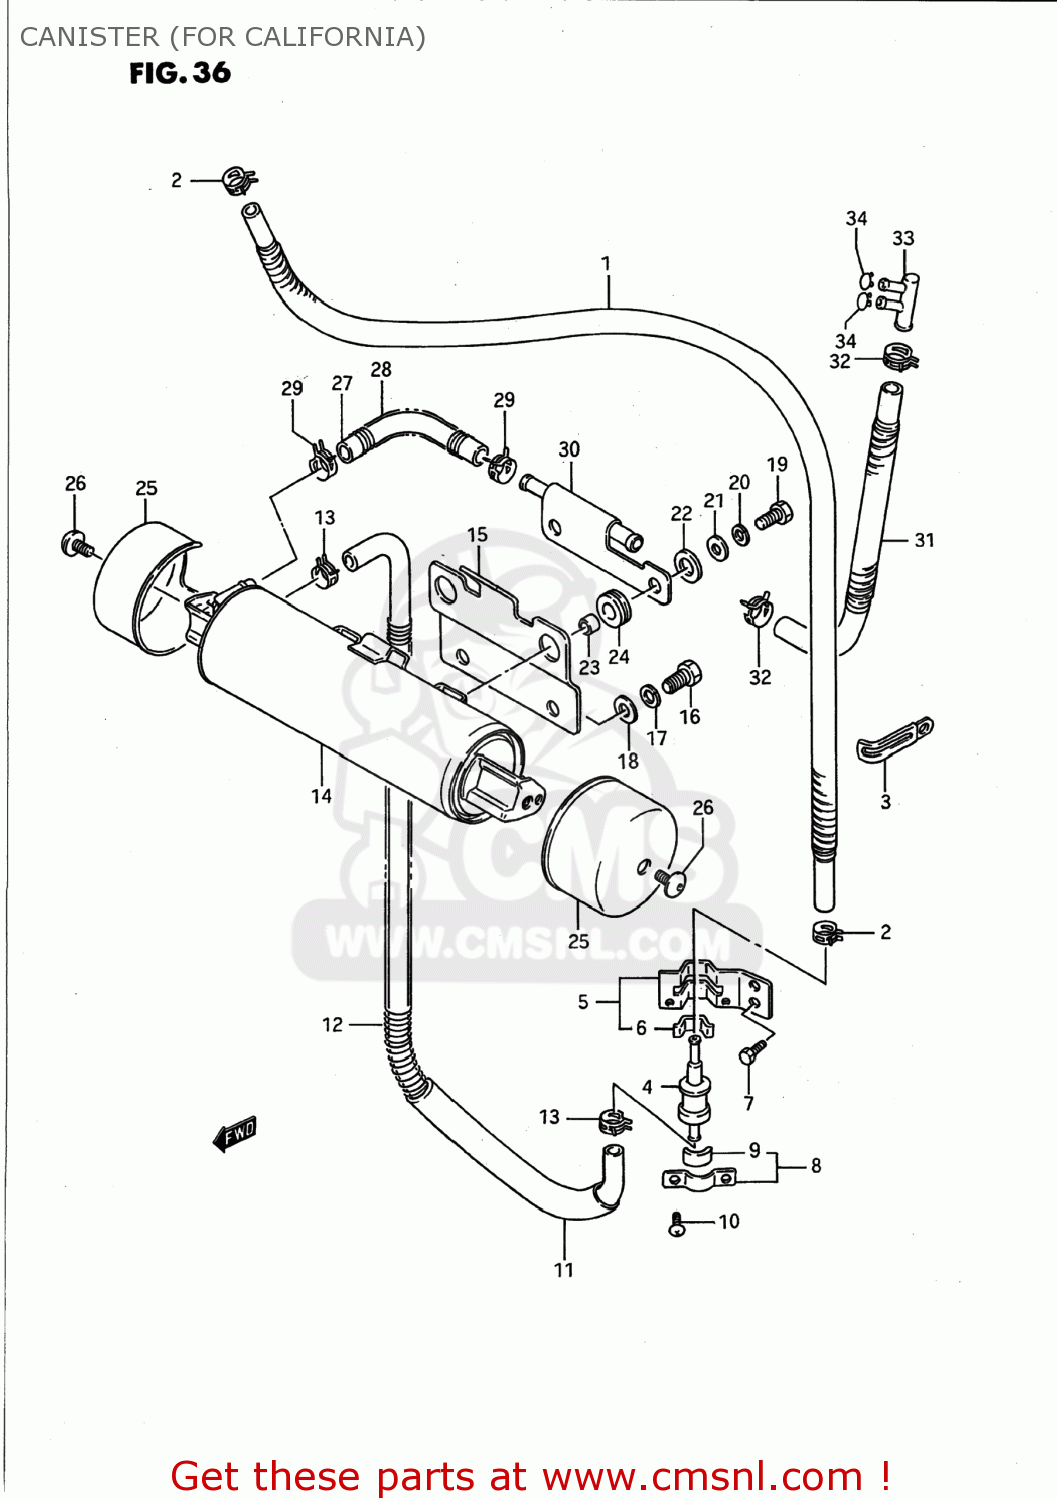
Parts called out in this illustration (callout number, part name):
1	HOSE,JOINT FUEL TANK
2	CLIP
3	CLAMP
4	VALVE,FUEL TANK BREATHER
5	BRACKET,TANK BRTHR VALVE
6	CUSHION
7	BOLT
8	PLATE,FUEL TANK BREATHER NO.2
9	CUSHION
10	SCREW
11	HOSE,VALVE & CANISTER JOINT
12	SPRING
13	CLIP
14	(CA) CANISTER ASSEMBLY,CHARCOAL
15	PLATE,CANISTER FITING
16	BOLT
17	WASHER,LOCK
18	WASHER
19	BOLT
20	WASHER,LOCK
21	WASHER
22	WASHER(6.5X22X1.6)
23	SPACER(6.1X9X7.5)
24	CUSHION
25	COVER,CANISTER
26	SCREW(6X10)
27	HOSE,CANISTER PIPE JOINT
28	SPRING
29	CLAMP
30	PIPE,CANISTER
31	(CA) HOSE,PIPE JOINT
32	CLAMP
33	SEPARATOR
34	CLIP
